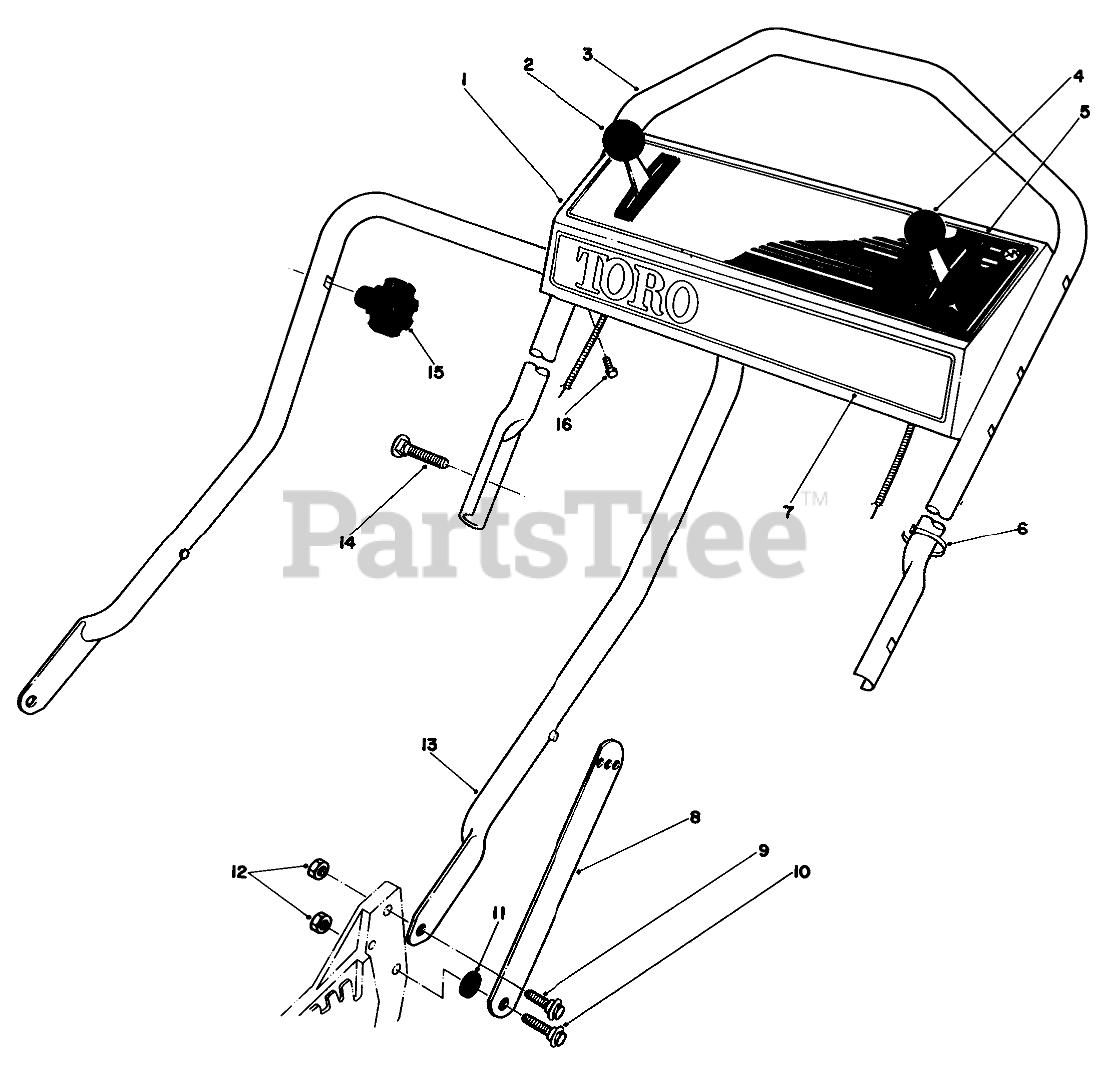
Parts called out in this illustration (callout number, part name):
1	Panel-Control (Incl. Ref. #5)
2	GROUND SPEED CONTROL
3	UPPER HANDLE
4	SERVICE THROTTLE CONTRO
5	Decal-Instruction Panel
6	TIE-CABLE
7	Decal-Toro
8	Handle Latch
9	SCREW-SHOULDER
10	SCREW-SHOULDER
11	SPACER
12	NUT-LOCK, NI
13	Handle-Lower
14	5/16-18 X 2 HNDLE SCREW
16	SCREW-HWHTF
